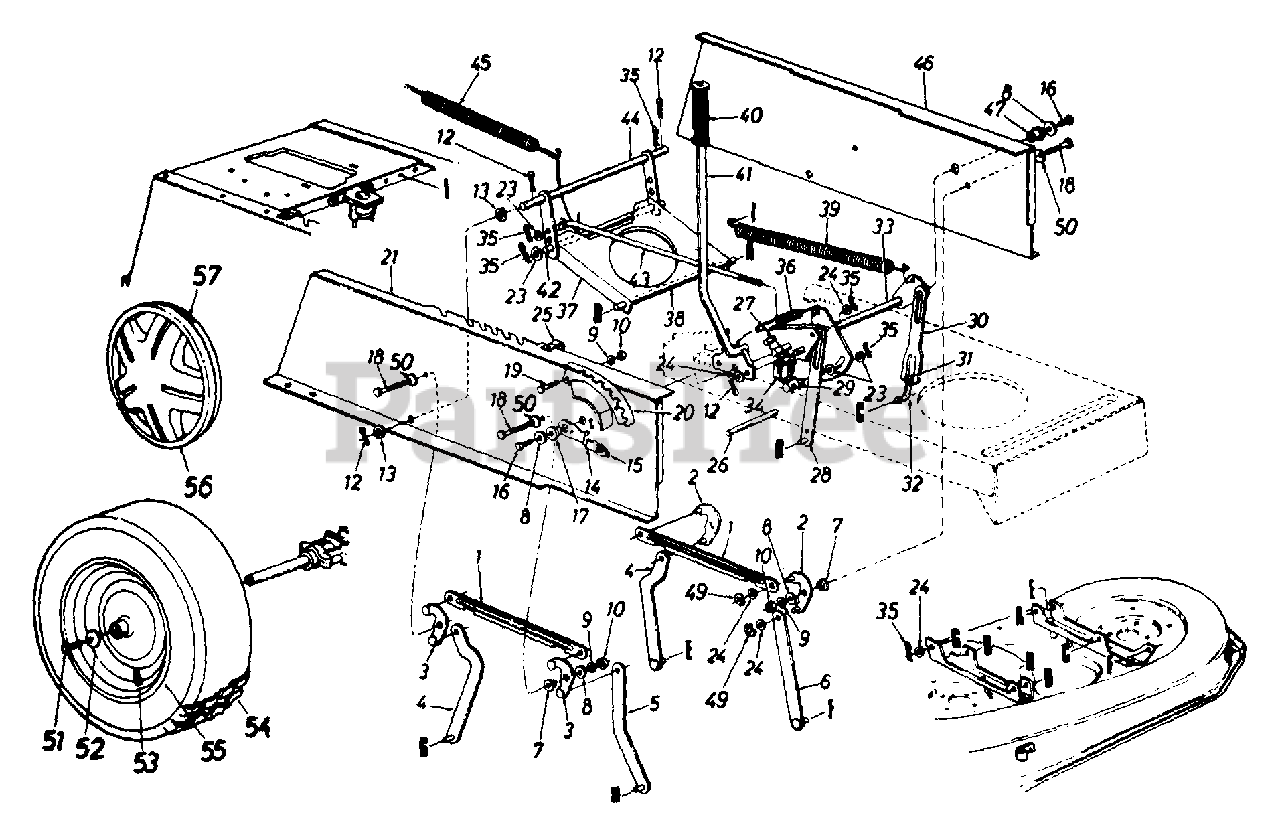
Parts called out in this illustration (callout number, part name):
1	Connecting Rod
2	Pivot Link Ass'y.- L.H.
3	Pivot Link Ass'y.- R.H.
7	Shld. Spacer.318" I.D.
8	Fl-Wash. .344" I.D. x .62" O.D.
9	L-Wash. 5/16" I.D.
10	Hex Nut 5/16-18 Thd.
12	Cotter Pin 1/8" Dia.
13	Fl-Wash. .635" I.D. x 1.0" O.D.
14	Height Adj. Stop Lever Ass'y.
15	Knob
16	Hex Wash. TT-Tap Scr. 5/16-18 x .75" Lg.
17	Flange Brg. .63" I.D.
18	Hex Wash. Hd. Scr. 5/16-18 x .875" Lg.
19	Hex Bolt 5/16-18 x .75" Lg.
20	Index Brkt.
24	Fl-Wash. .531" I.D. x.93" O.D.
25	Clamp
26	Running Board Rod
27	Hex Wash. Hd. Tap Scr.
31	Hex Nut 1/2-20 Thd. (Gr. 5)
32	Lift Link Adjuster
35	Inter. Cotter Pin 3/8" Dia.
36	Extension Spring
39	Extension Spring
40	Grip (Lift Handle)
41	Deck Lift Handle Ass'y.
42	Shaft 3/8" Dia. x 9.34" Lg.
43	Disengagement Rod
44	Stabilizer Shaft Ass'y.
45	Extension Spring 7.58" Lg.
46	Upper Frame - L.H.
47	Flange Brg. .632" I.D.
49	"E"-Ring
50	Bell-Wash. .325" I.D.
51	Hex Bolt 5/16-24 x .75" Lg.
52	Bell-Wash. .345" I.D. x .88" O.D.
53	Air Valve
55	Rim Only
56	Hub Cap (Gray)
57	Spring Clip
